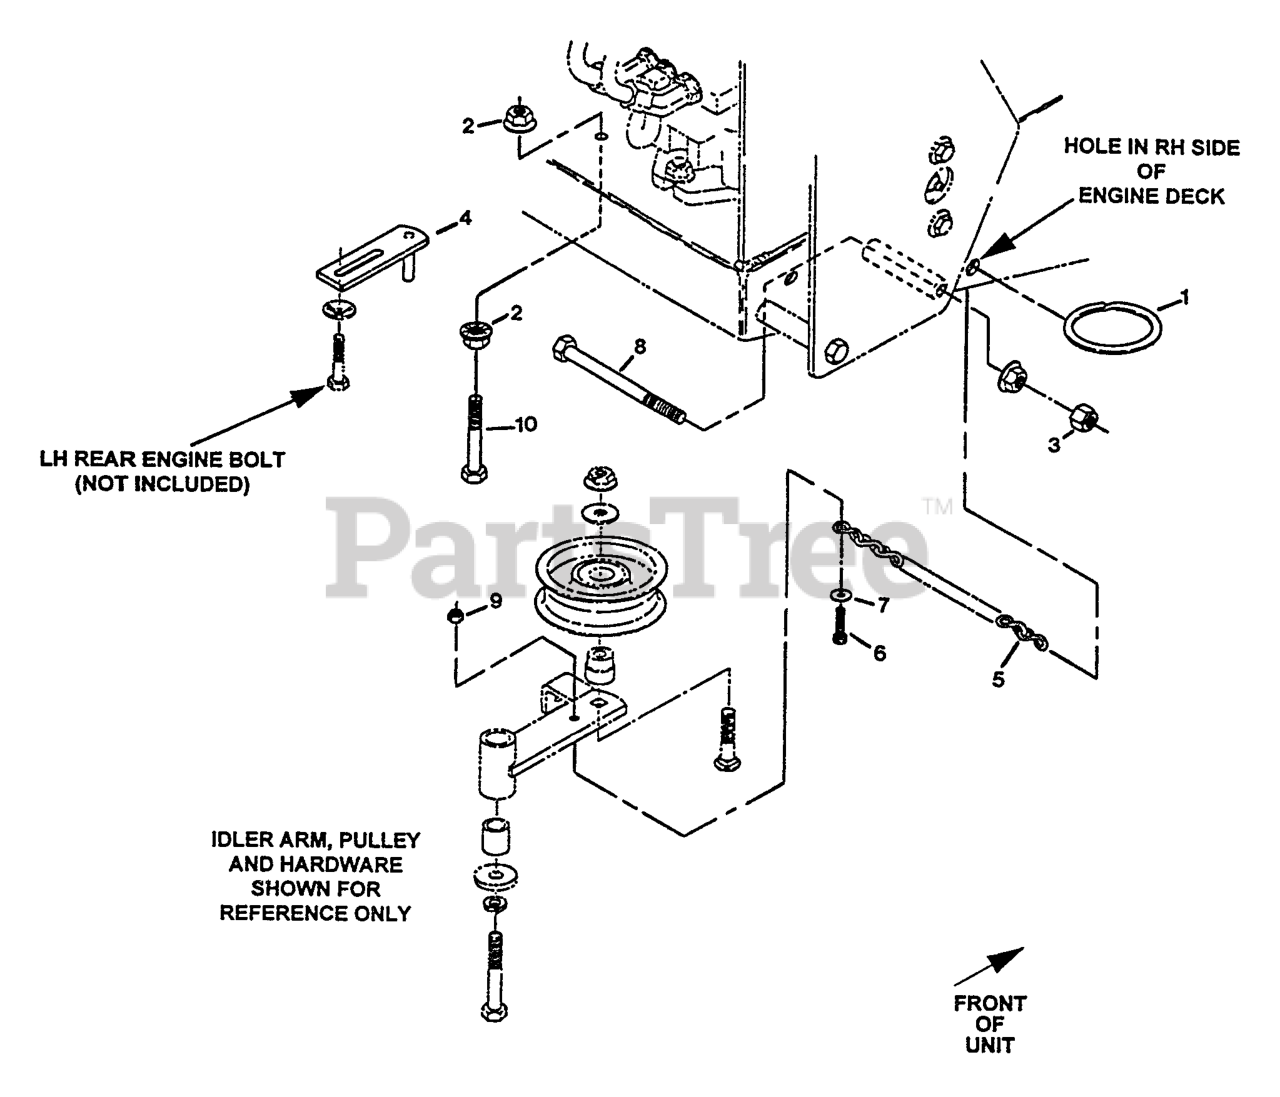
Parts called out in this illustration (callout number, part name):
1	RING-SPLIT
4	GUIDE-BELT
5	CHAIN-LINK, TWIST
6	SCREW-HSH
